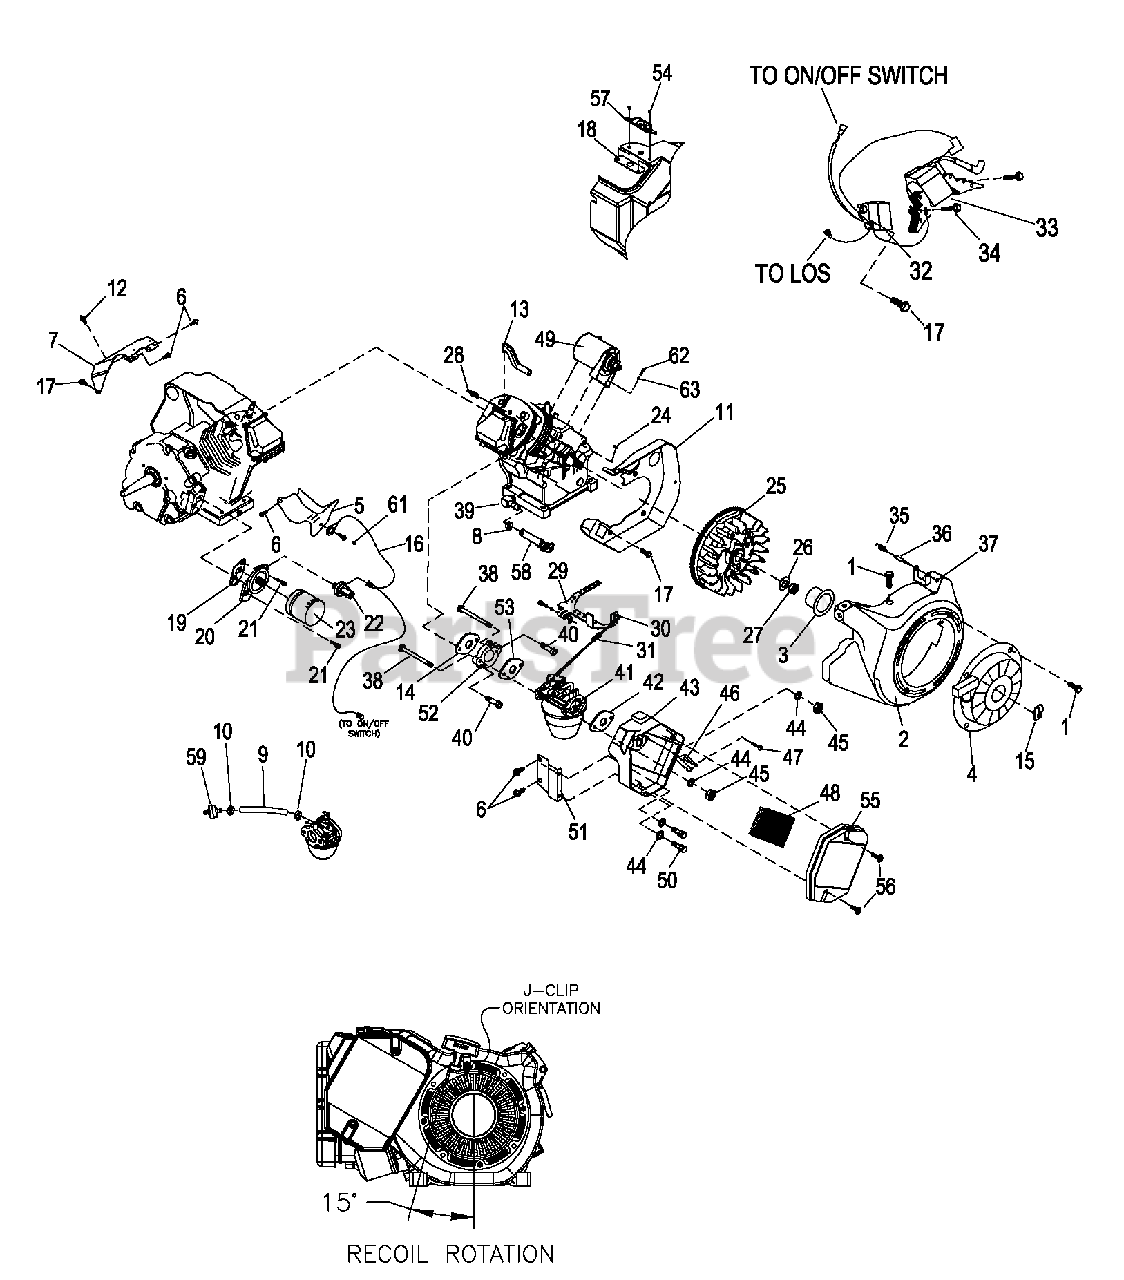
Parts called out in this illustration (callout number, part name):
1	SCREW HHTT M6-10X8ZYC
2	ASSEMBLY, BLOWER HOUSING
3	PULLEYSTARTER LARGE FRAME
4	RE COIL STA RTE R LARG E FRAME
5	WRAPPER, BOTTOM 12 HP HS
6	SCREW HHTT M6-10 X10 YELLOW C HROME
7	WRAPPER, TOP REGULARSTEEL
8	CLAMP,HOSE OET1KER STPLSS18.5
9	FUEL HOSE, 250 MM LONG
10	CLAMP HOSE BAND .41
11	BACKPLATE
12	SCREW, HHTT5/16-18X1/2" CLEAR
13	HOSE, BREATHER GH410ENGINES
14	GASKET, INTAKE ADAPTER
15	CLIP-J, VINYL COAT
16	WIRE HARNESS 410 ENGINE SWITCH WIRING
17	SCREW HHFCM6-1.0 X12
18	BACK PLATE
19	GASKET,OIL FILTER ADAPTER
20	ADAPTER, OIL FILTER
21	SCREW, SHC M8-1.25 X 30 G12.9
22	SWITCH, HOBBS OIL PRESSURE5PSI
23	FILTER, OIL BLACK 75 LONG
24	KEY, WOODRFF 4X19D
25	FLYWHEEL RING GEAR 27DEG
26	WASHER,BELV-20 X22
27	NUT HEX M20-1.5 G8YLW CHROME- FLYWHEEL
28	SPARKPLUG, CHAMPION RC14YC 0.030"
29	ASSEMBLY,GOVERNORLEVER 12HP
30	ROD, GOVERNOR CONTROL
31	SPRING, ANTI-LASH
32	OIL PRESSURE SHUTDOWN MODULE
33	ASSEMBLY, IGNITION ADV NO DIODE GH410
34	SCREW HHFCM6-1.0X25G88
35	SPRING GOVERNOR50HZ
36	BOLT, GOVERNOR ADJUSTMENT M5
37	NUT, HEXLOCK M5-0.8NYLON INSERT ZINC
38	BOLT, CARBURETOR MOUNTING
39	BARBED ELBOW 90 DEG 3/8" NPT X 3/8"
40	FLANGE HEAD SCREW, SHC M6-1.0X 20 G8.8ZP
41	CARBU RETOR ASSEM BLY, 410HS
42	GASKET, AIRCLEANER
43	BASE, AIRCLEANER 410 XP PORT
44	WASHER, FLAT M6
45	NUT, HEXLOCK M6-1.0 NYLON INSERT
46	PLATE, SRTBACK
47	SCREW HWHTF 8-18X0.5 HI-LOW
48	ELEMENT, AIR FILTER
49	STARTER, ASSEMBLY
50	SCREW, HHC M6-1.0X16W/ LOCKWASHER
51	BRACKET, AIR CLEANER
52	ADAPTER, "K"
53	GASKET, CARBURETOR/MANIFOLD
54	RIVET, 1/8"
55	COVER, AIR CLEANER 13GN
56	BOLT, AIR CLEANERCOVER
57	BRACKET, CHOKE CABLE
58	ASSYOIL DRAIN HOSE, 6" LONG ORANGE
59	FUEL FILTER
61	GROMMET
62	SCREW SHCM8-1.25X40C8.8
63	WASHER, LOCKM8-5/16
